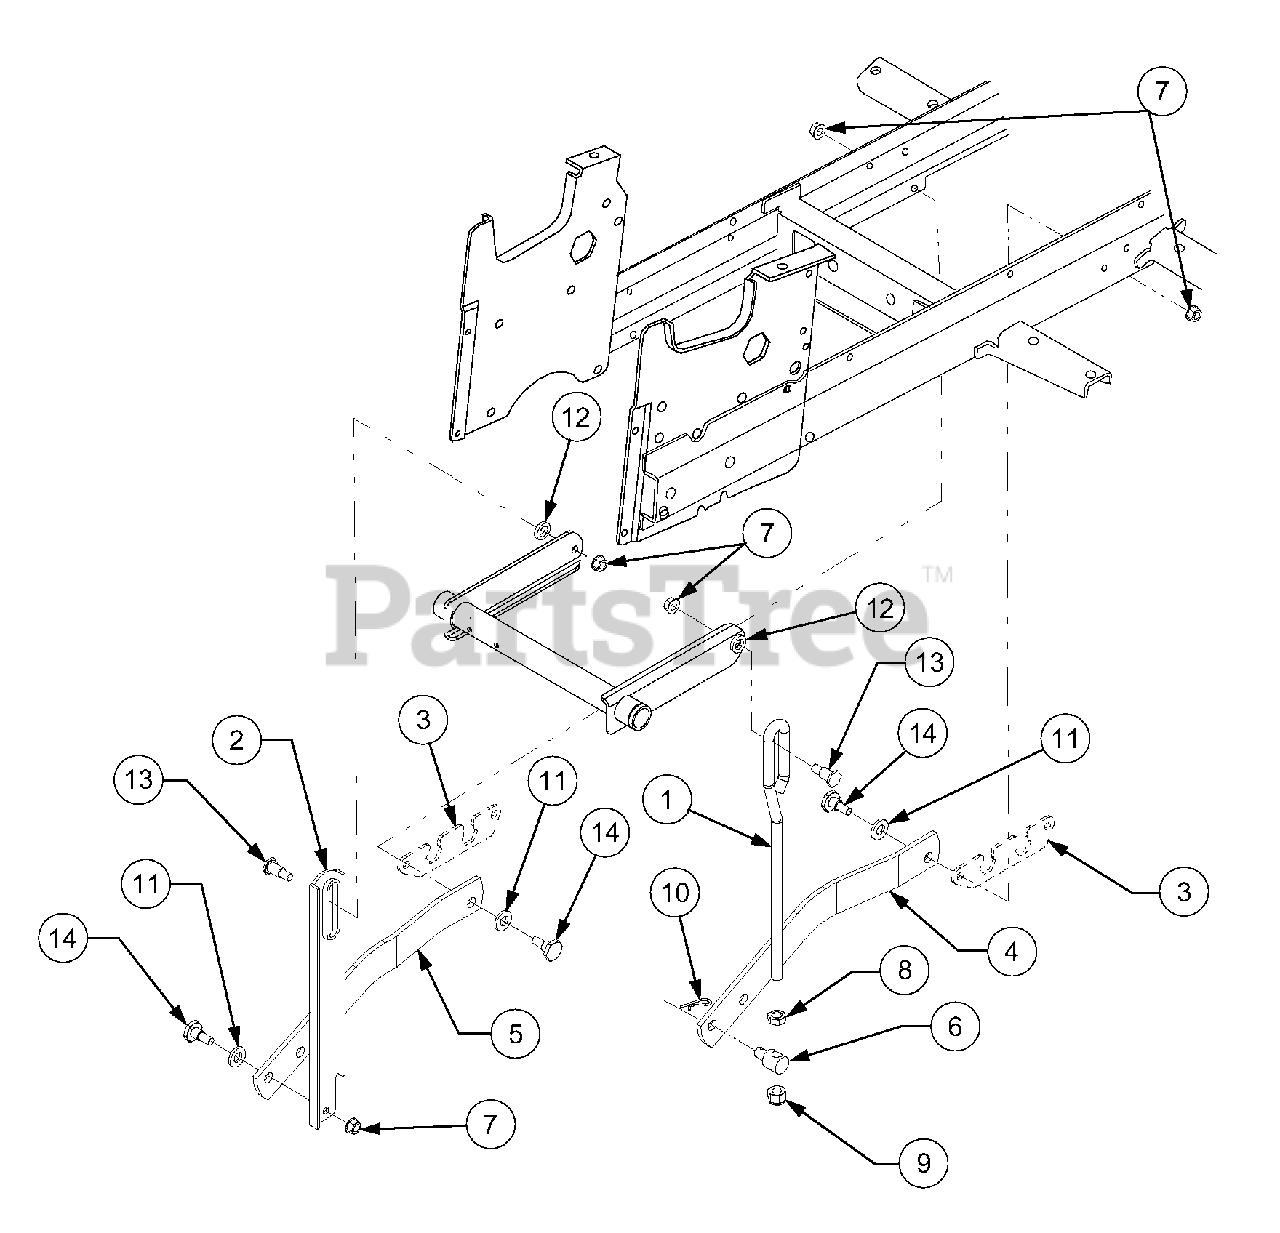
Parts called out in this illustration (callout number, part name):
1	Rod, Lift Link
7	Nut, Hex Flange Lock, 3/8-16
8	Nut, Hex Jam, 1/2-13 GR5
9	Nut, Hex Insert Lock, 1/2-13
10	Pin, Internal Cotter
11	Washer, Flat, .5 x 1.5 x .15
12	Washer, Flat, .531 x .875 x .15
13	Bolt, Shoulder
14	Bolt, Shoulder
